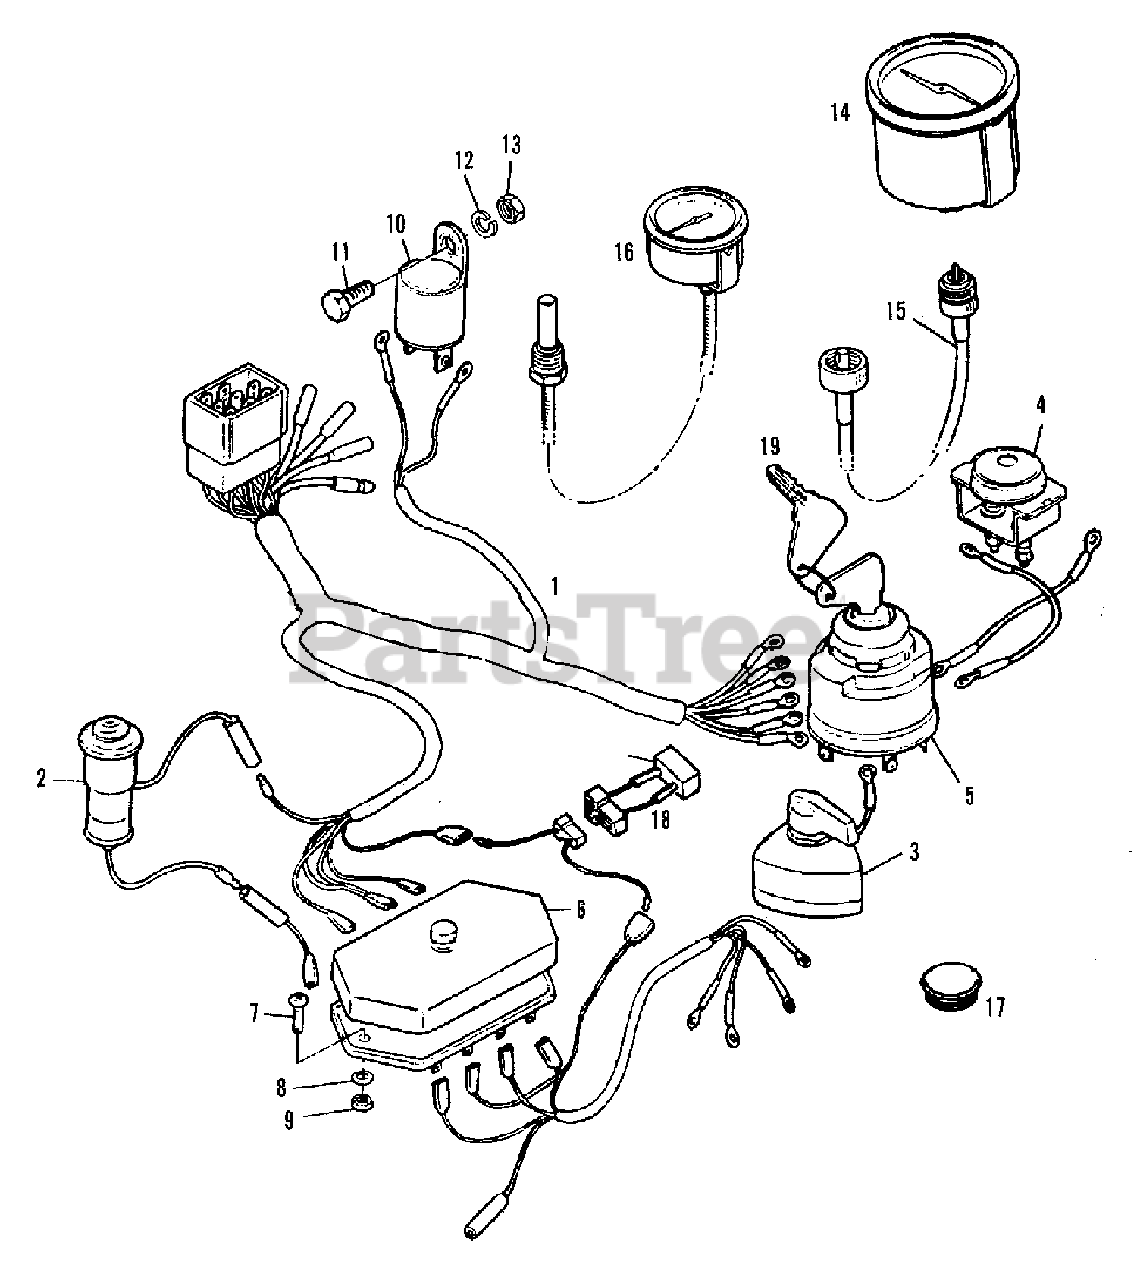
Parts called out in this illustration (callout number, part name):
2	CONDENSER
3	SWITCH, lighting
5	SWITCH, main
6	BOX, fuse
7	SCREW, M5 x 14
8	LOCKWASHER, M5
10	FLASHER UNIT
11	CAPSCREW, M6 x 16
12	LOCKWASHER, M16
14	METER, tach and hour
16	GAUGE, water temp.
